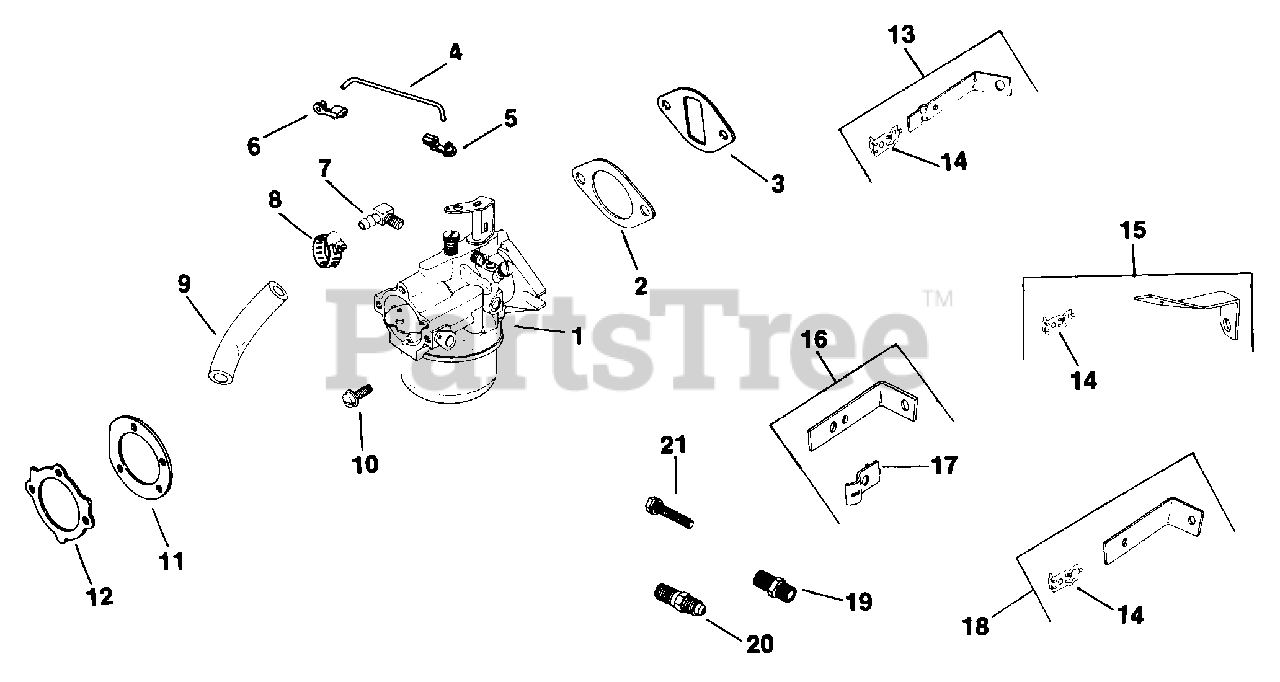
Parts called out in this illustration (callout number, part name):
1	CARBURETOR - USE 47 853 04
1	CARBURETOR - USE 47 853 30
1	KIT, CARBURETOR W/LINKAGE
3	GASKET, CARBURETOR
6	BUSHING - USE 25 158 11
7	CONNECTOR, 90 DEG. HOSE
10	SCREW, SLT HD 5/16-18X1" - DISCONTINUED
13	BRACKET
